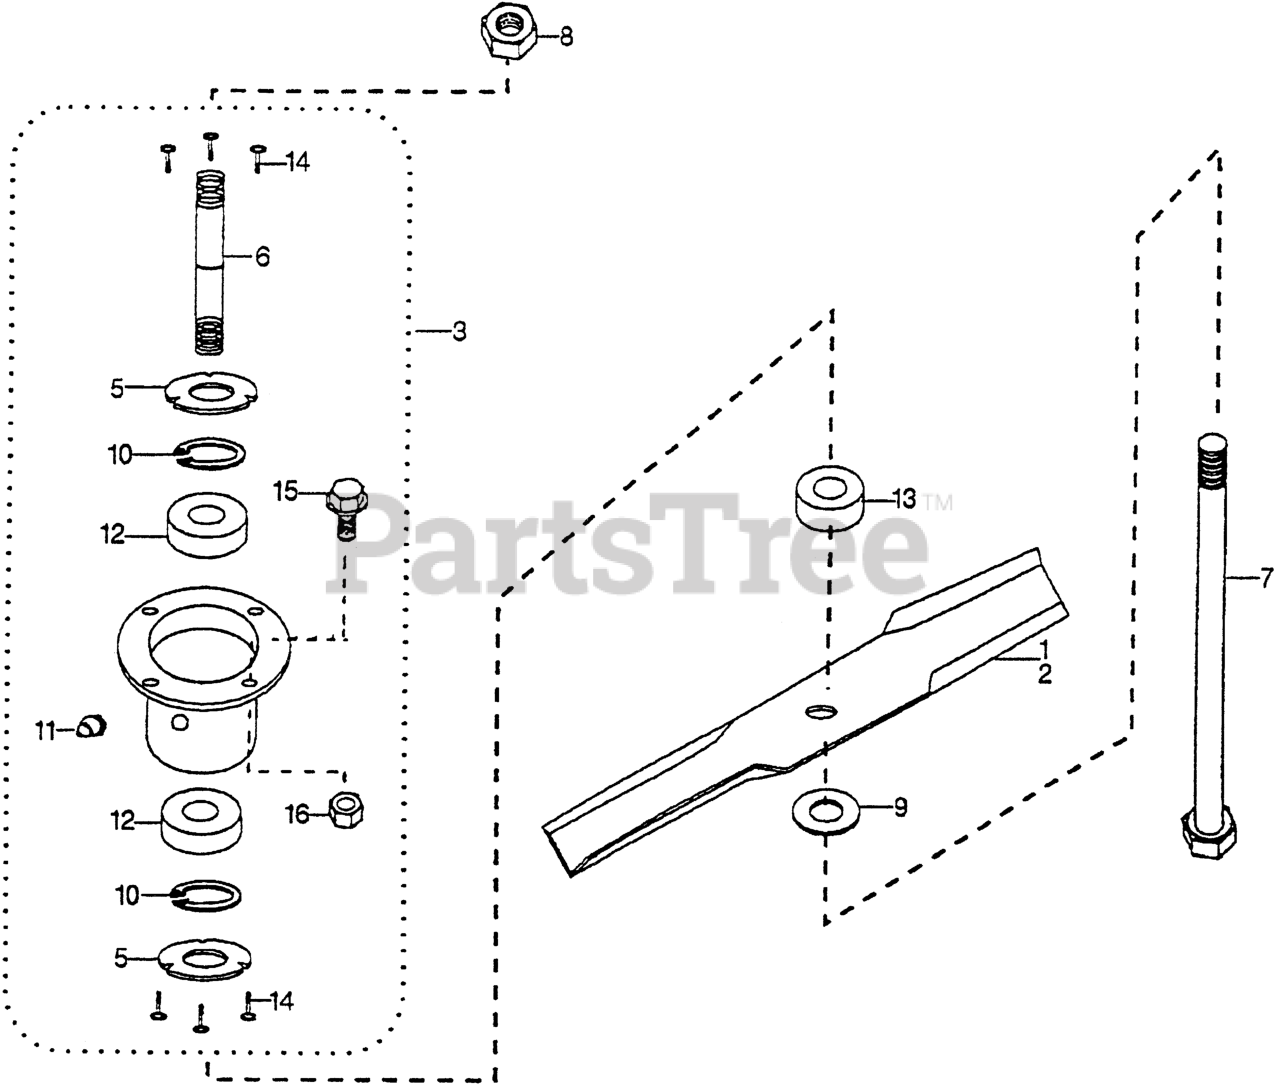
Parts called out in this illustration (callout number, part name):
1	BLADE, HIGH LIFT (18")
3	HOUSING ASSY., BLADE BEARING
5	CAP, BEARING HOUSING
6	SHAFT, BLADE
7	BOLT, BLADE
8	JAM NUT (5/8"-18)
9	WASHER, BLADE
10	RING, SNAP
11	NIPPLE, GREASE
12	BEARING, BLADE SHAFT
13	COLLAR, BLADE (5/8")
